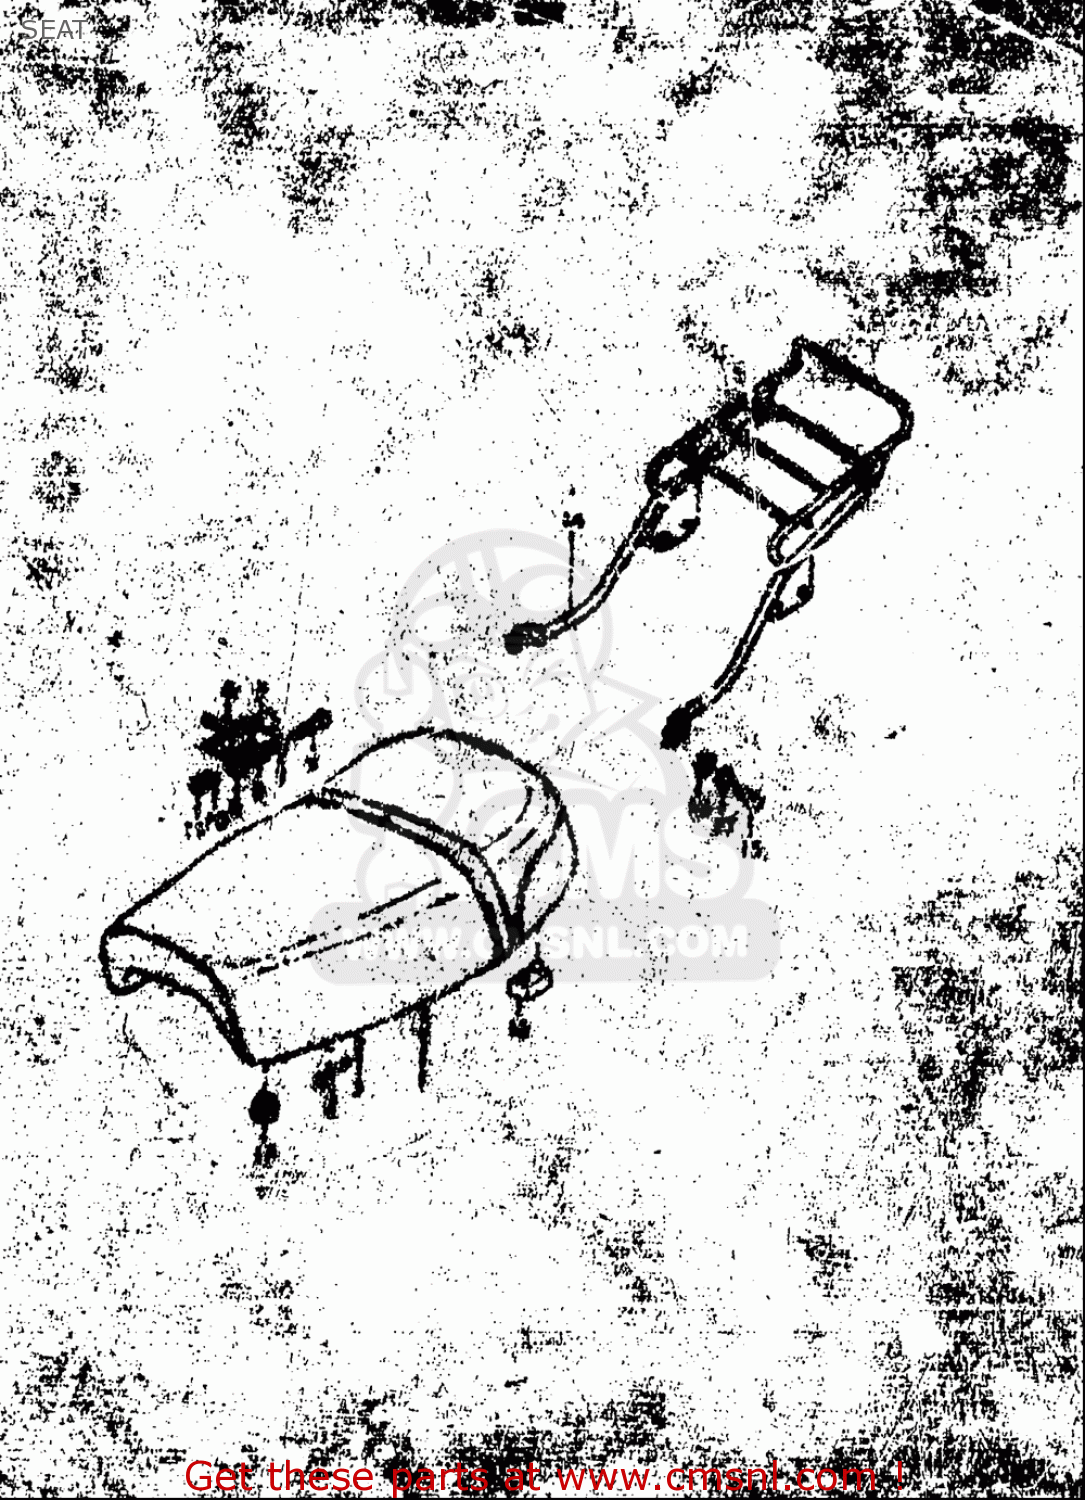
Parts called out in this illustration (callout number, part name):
2	PIN
3	PIN
5	BUSHING
7	STRIKER,SEAT LOCK
8	SPRING
12	CUSHION
13	CUSHION(11.5X22X20)
15	BOLT
